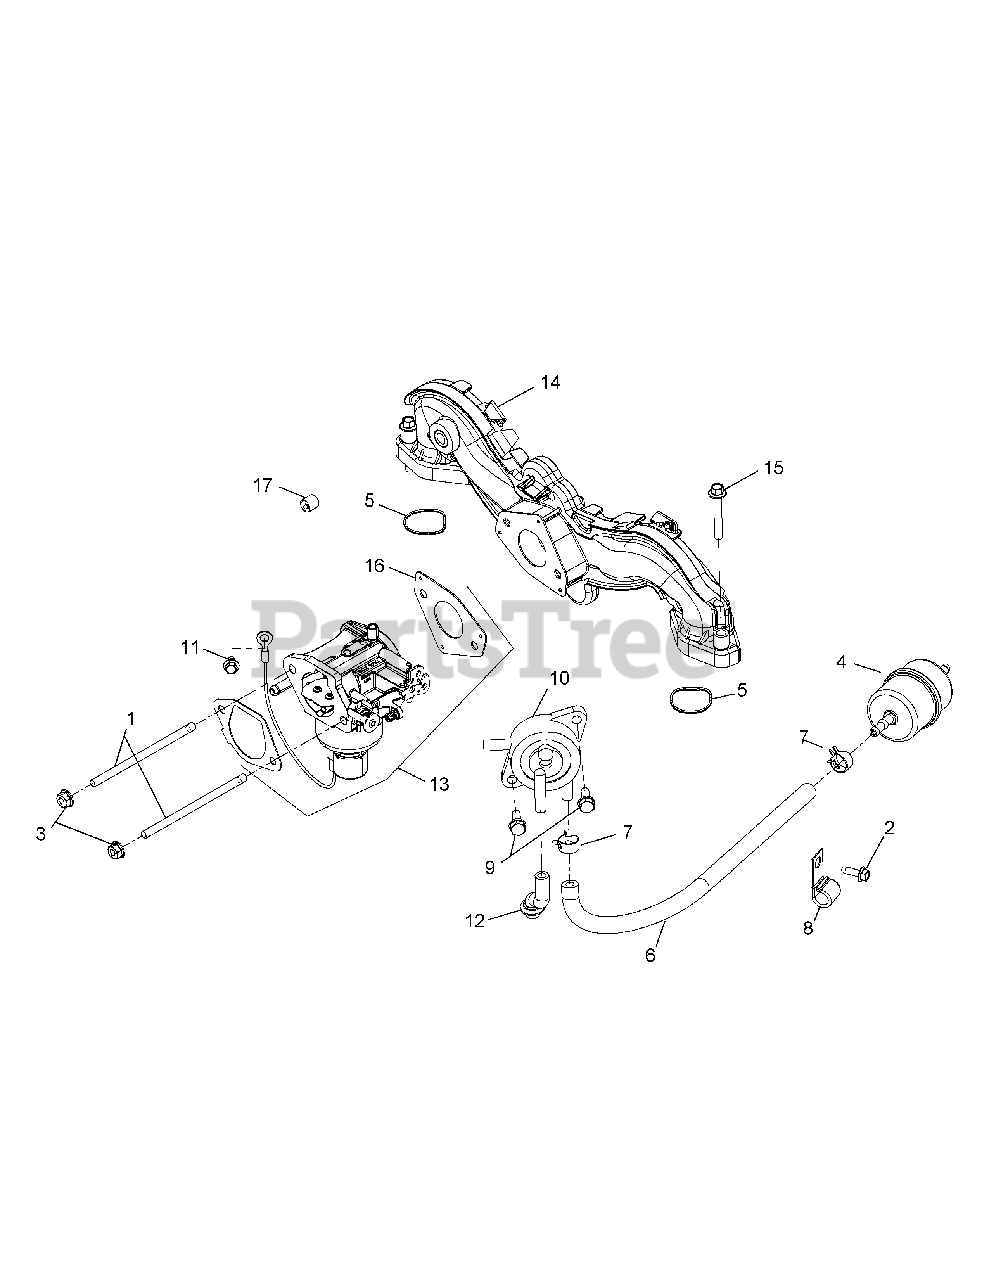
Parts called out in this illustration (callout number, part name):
2	Thread Forming Screw
3	Flange Nut, M6 x 1.0
4	Fuel Filter
5	Intake Port O-Ring
6	Fuel Line, 24"
7	Spring Hose Clamp
9	Tap Screw, M6 x 1.7 x 18
11	Thread Forming Screw
12	Pulse Pump Hose
13	Carburator Kit
14	Intake Manifold Kit
15	Flange Screw, M6 x 1.0 x 40
16	Carburetor Gasket
17	Pipe Plug, 1/8
